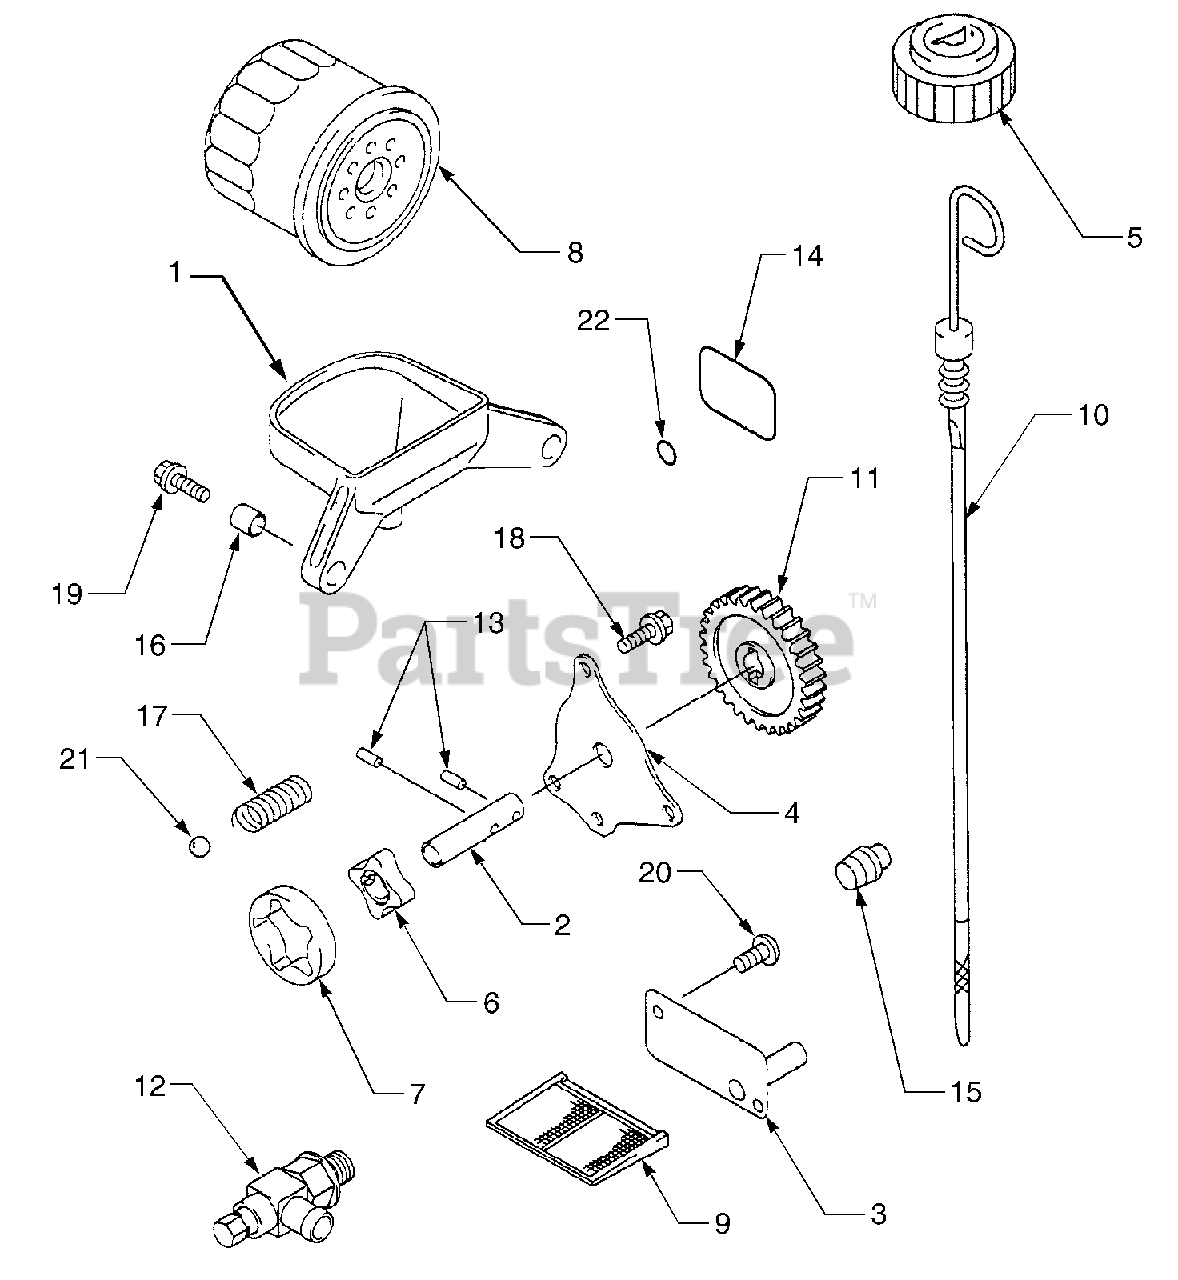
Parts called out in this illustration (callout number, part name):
1	Receiver, Oil
2	Shaft, Oil Pump
4	Cover, Oil Pump
5	Cap, Oil Filler
6	Rotor, Pump Inner
7	Rotor, Pump Outer
8	Filter, Oil
9	Screen, Oil Filter
10	Dipstick, Engine OIl
12	Fitting, Oil Drain
16	Collar, 8.2 x 10 x 10
17	Spring, Relief Valve
18	Bolt, Flanged
19	Bolt, Flanged
21	Ball, Steel
